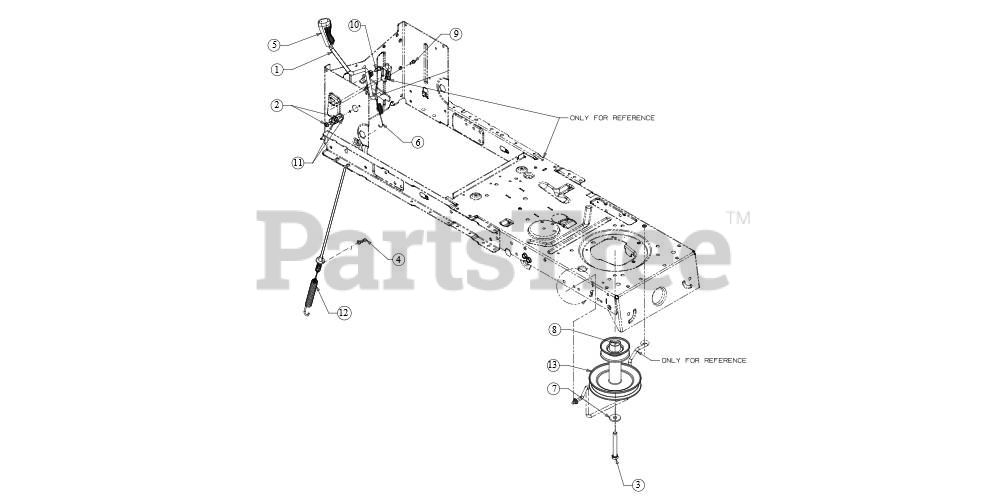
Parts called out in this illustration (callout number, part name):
2	SCREW 1/4-20 X.500
3	SCREW 7/16-20 x 3.25 GR5
4	BOW TIE COTTER PIN 1/4-5/16
5	HANDLE GRIP
6	EXTENSION SPRING
7	FLAT WASHER .445 X 1.248 X .170
9	SHOULDER SCREW
10	SHOULDER SCREW
11	PTO BEARING
12	DECK ENGAGEMENT CABLE
13	ENGINE PULLEY 3.39 X 6.12 DIA
